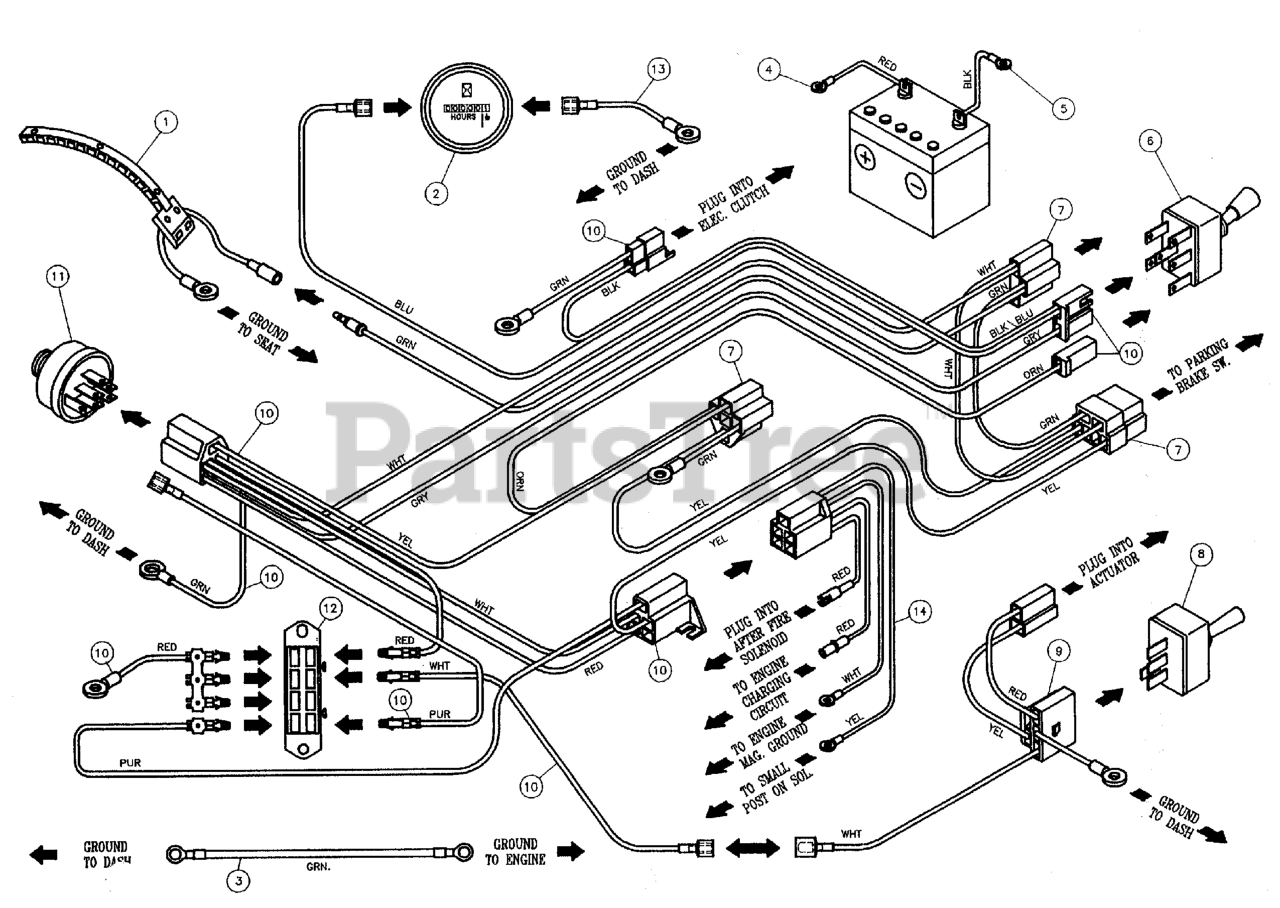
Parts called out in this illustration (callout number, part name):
1	Seat Switch
2	HOUR METER
3	DASH GROUND WIRE
4	POSITIVE (+) BATTERY CABLE, 30"
5	BATTERY CABLE, NEG, 22, 1/4-5/16
6	SWITCH, Electric Clutch
7	Relay Clutch Harness
8	SWITCH, Actuator
9	Actuator Harness
10	Rider Main Harness
11	SWITCH, IGNITION, 6 POST
12	Fuse Block
13	HOUR METER GROUND WIRE
14	Briggs Adapter Harness
